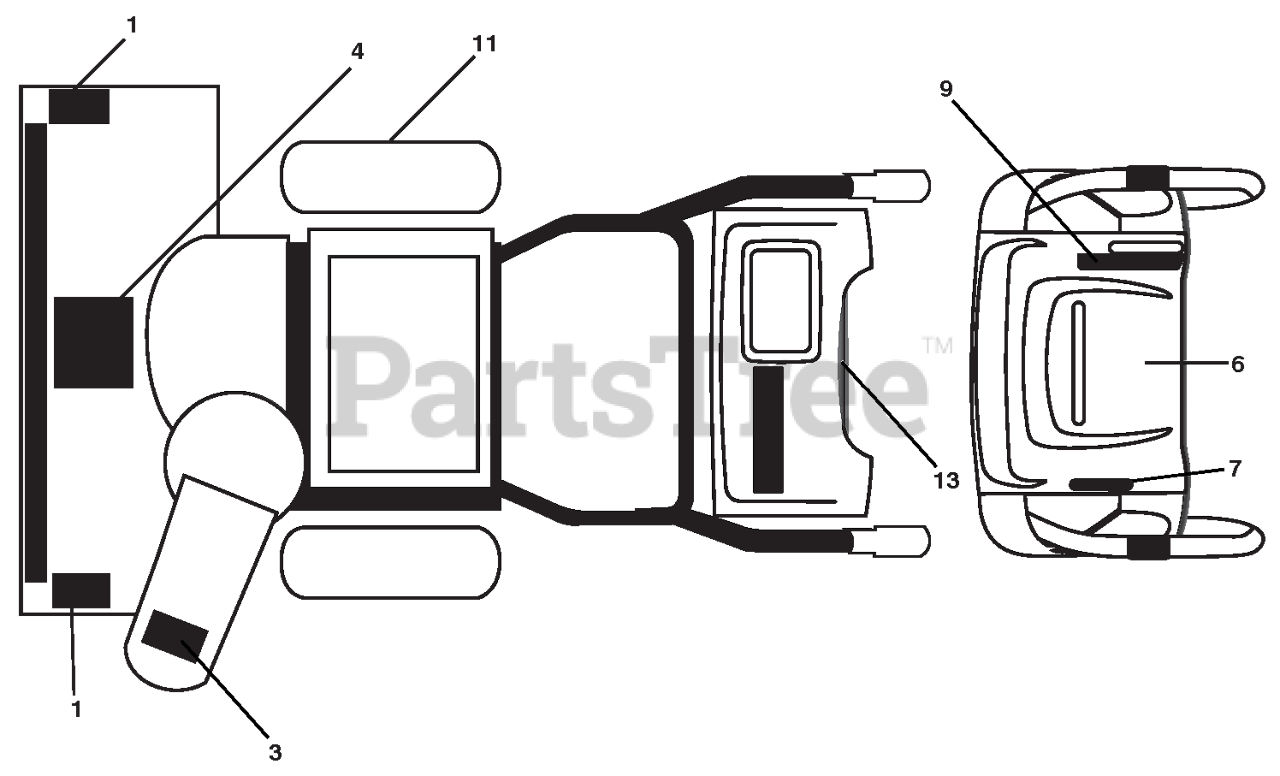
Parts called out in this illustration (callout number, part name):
1	DECAL.AUGER.SAFETY.
3	DECAL.CHUTE.SAFETY.
4	DECAL.AUGER."
7	DECAL.CONS.LH.REMOTE.INST.GRY
9	DECAL.CONS.RH.INST.GRY
11	DECAL.BELT.GUARD.
13	DECAL.FENDER
